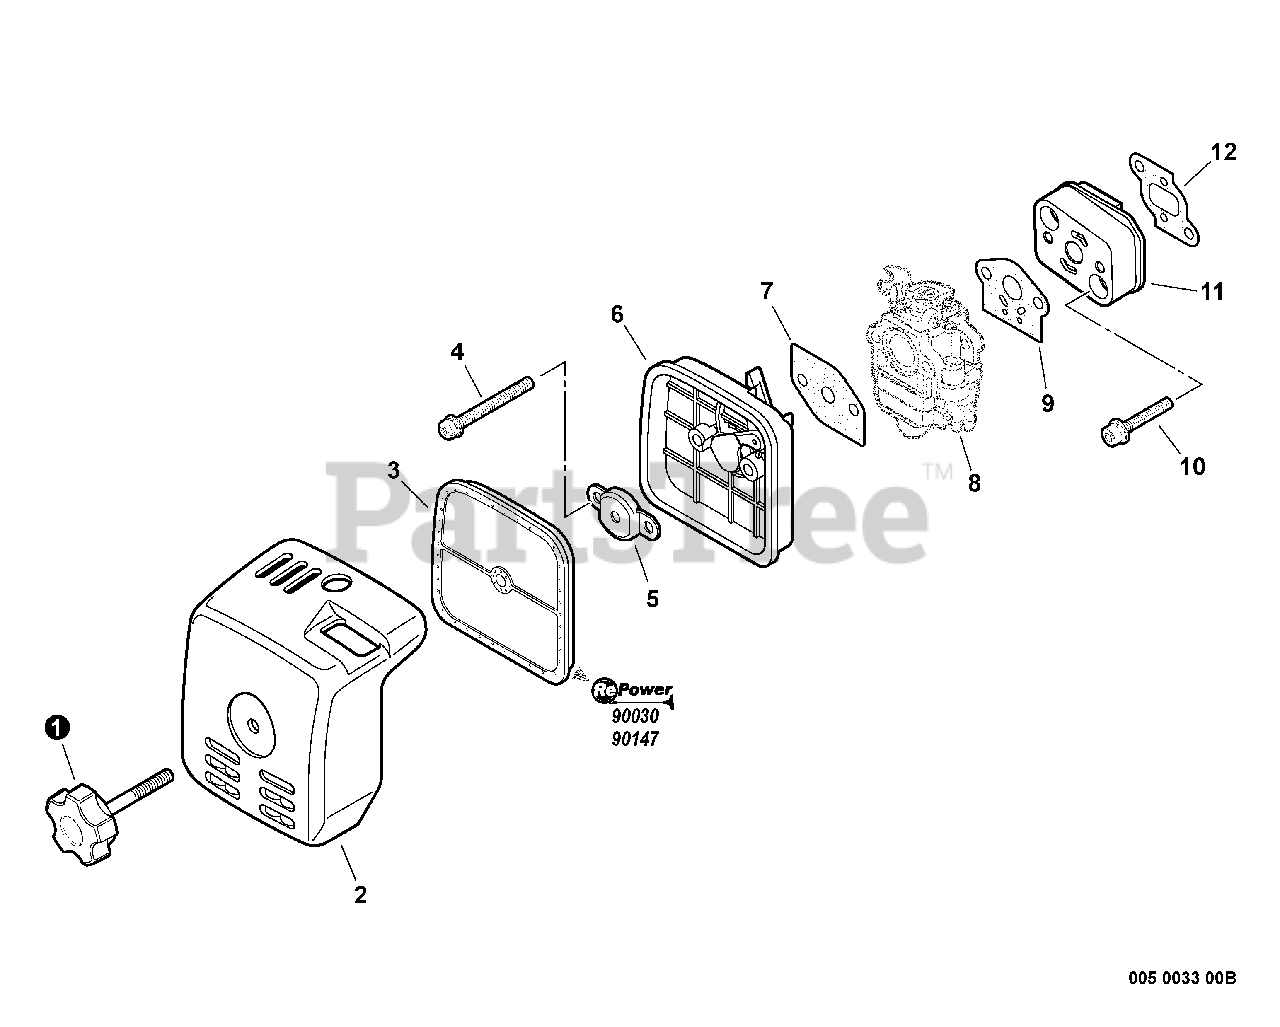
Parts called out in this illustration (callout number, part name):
1	THUMBSCREW
2	COVER, AIR FILTER
3	FILTER, AIR - HEAVY DUTY
4	SCREW - 5X60
5	PLATE, PREVENT
6	CASE, AIR FILTER
7	GASKET, INTAKE
8	CARBURETOR
9	GASKET, INTAKE
10	SCREW - 5X25
11	INSULATOR, INTAKE
12	GASKET, INTAKE
13	RePower FILTER KIT
14	RePower TUNE-UP KIT
